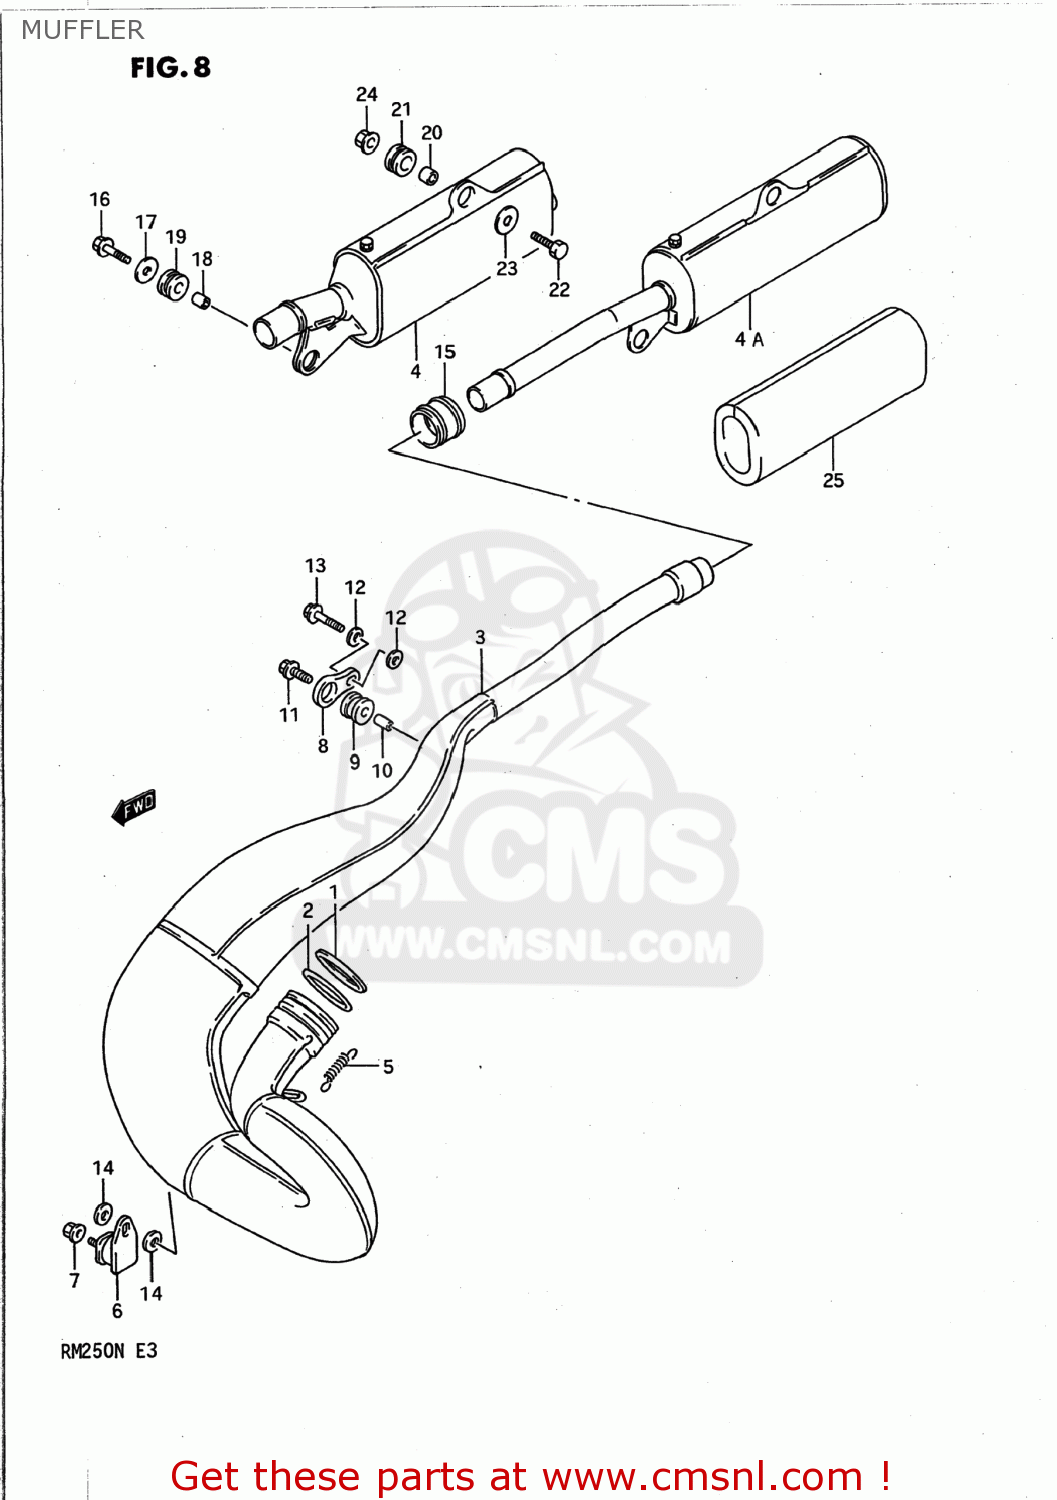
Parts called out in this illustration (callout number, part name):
1	WASHER,EXHAUST PIPE
2	O RING,EX PIPE
3	BODY,MUFFLER,FIRST
4	BODY,MUFFLER
4A	BODY,MUFFLER
5	SPRING
6	DAMPER,MUFFLER SUPPORT
7	NUT
8	PLATE,MUFFLER MTG
9	CUSHION,MUFFLER
10	SPACER(6.4X9X16)
11	BOLT
12	WASHER (6.5X20X1.2)
13	BOLT
14	WASHER
15	CONNECTOR,MUFFLER
16	BOLT
17	WASHER (6.5X29X1.6)
18	SPACER (6.8X10X9)
19	CUSHION
20	SPACER (8.1X11.5X13)
21	CUSHION
22	BOLT
23	WASHER (8.5X29X1.6)
24	NUT
25	SILENCER,MUFFLER
